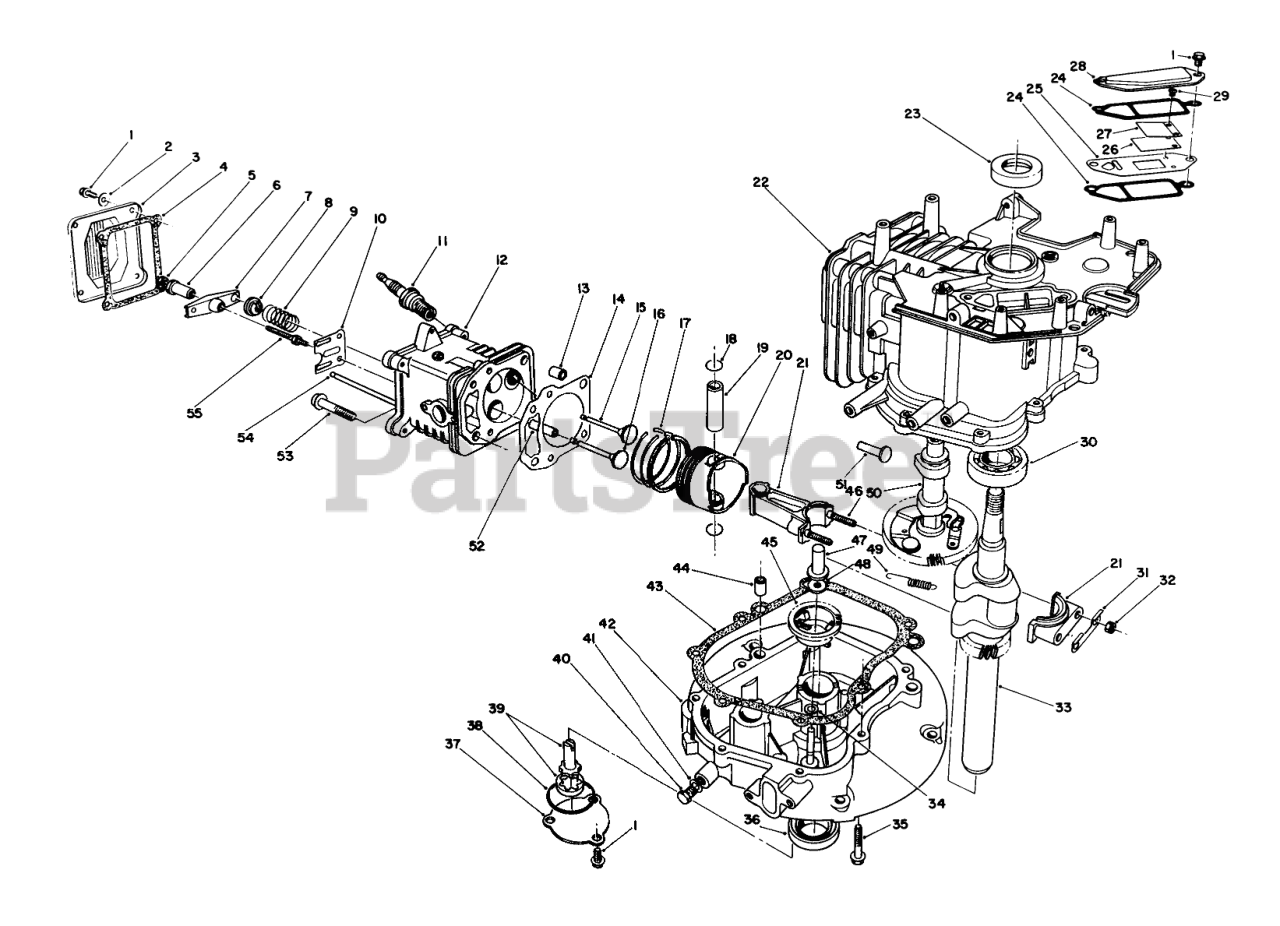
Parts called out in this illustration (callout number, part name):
2	WASHER
3	COVER
4	GASKET
6	PIVOT
8	RETAINER
9	SPRING
10	GUIDE
11	SPARK PLUG
12	Head-Cylinder (Incl. Ref. #52)
14	Gasket-Cylinder Head
15	VALVE-INTAKE
16	VALVE-EXHAUST
17	RING SET
18	CIRCLIP
20	PISTON
21	Connection Rod Assembly (Incl. Ref. #31, 32, & 46)
22	Block-Engine (Incl. Ref. #23, & 30)
24	GASKET
25	Plate-Breather
26	Reed Valve Assembly (Incl. Ref. #25, 27 & 29)
27	Retainer-Reed Valve
28	COVER
29	Screw-Reed Valve
30	BEARING
31	Plate-Lock
33	CRANKSHAFT
34	WASHER
37	COVER
38	O-RING
39	OIL PUMP
40	Plug-Oil Drain
41	GASKET
42	Crankcase
43	GASKET
45	Governor Flyweight Assembly
47	PLUNGER
48	WASHER
49	SPRING
50	Camshaft Assembly (Incl. Ref. #49)
51	TAPPET
52	GUIDE
